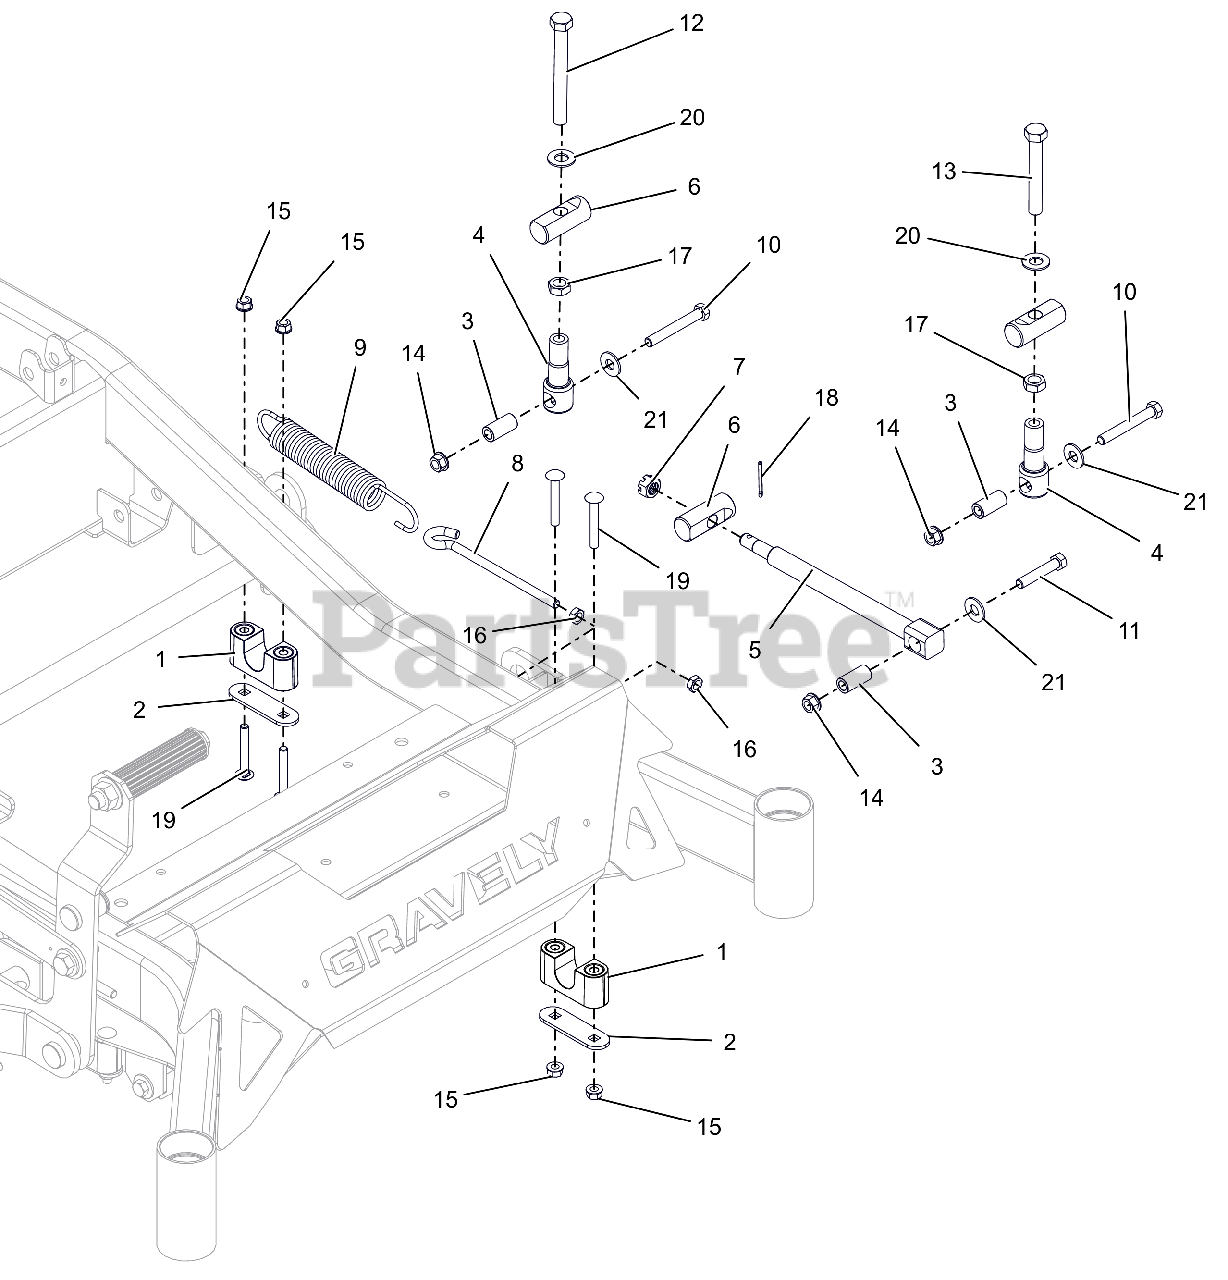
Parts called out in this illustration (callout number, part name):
1	ASM-BUSHING, DECK LIFT
2	PLATE, BEARING SUPPORT
3	SPACER, DECK LEVELING
4	LINK, DECK LIFT FORMED
5	DRAG,LINK-HD
6	PIN, DECK LIFT
7	NUT-SL .50-13
8	BOLT,.38-16 X 5.25-.62 DIA EYE
9	SG-TENS .162X1.25X8.25 WLD 25
10	BLT, HEX .38-16X2.75 G8 ZCC
11	BLT,HEX .38-16X2.00 G5 ZCC
12	BLT, HEX .50-13X4.50F G8 ZCC
13	BLT, HEX 0.5-13X3.5F GR5 ZCC
14	NUT-LK-TOP-FLG .38-16 ZC120
15	NUT,LK-CTR-FLG .31-18 GF ZCC
16	NUT-JAM .375-16 G2 ZCC
17	NUT-JAM .500-13 G2 ZCC
18	PIN,CTR.12X1.25EXTPRSQCT ZC120
19	BLT, RHSSN.31-18X2.25 G5 ZCC
20	WSHR, FLT .557X1.040X.102 ZCC
21	WSHR,FLT .438X1.00X.083 ZCC
